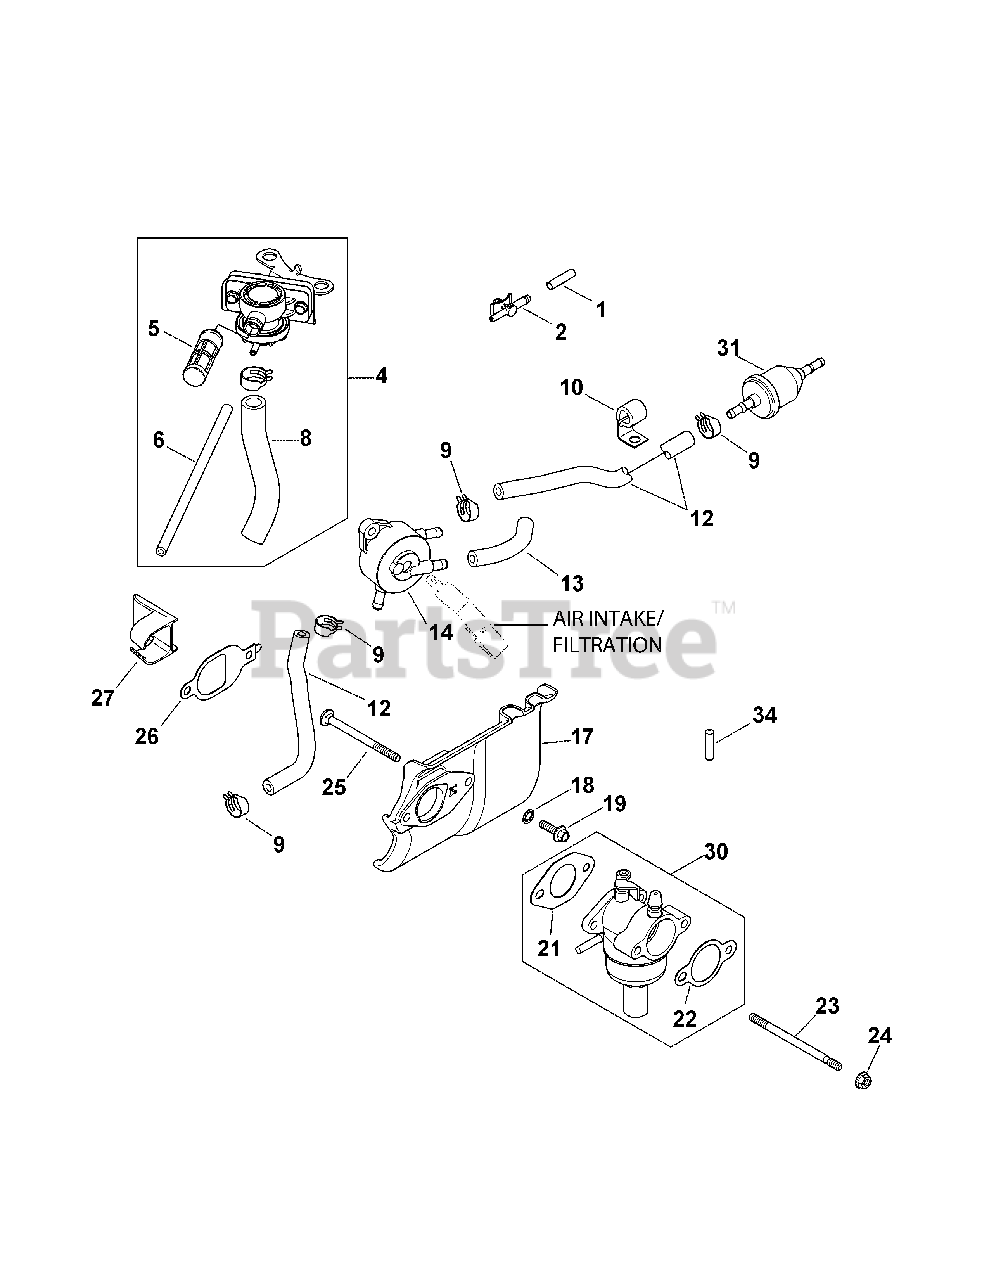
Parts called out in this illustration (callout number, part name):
2	SAI Connector
4	Fuse Block
5	Fuse Block
6	Fuse Block
8	Fuse Block
9	Hose Clamp, 1/2
10	Fuse Block
12	Fuel Line
13	Fuse Block
14	Fuse Block
17	Heat Deflector Kit
18	Int. Tooth Lock Washer, 1/4
19	Flange Screw, M6 X 1.0 X 20
21	Gasket, carburetor
22	Gasket, air cleaner
23	Stud, M6 X 1.0 X 100
24	Flange Nut, M6 X 1.0
25	Carburetor Stud
26	Heat Deflector Gasket
30	Carburetor Kit
34	not used in this application
